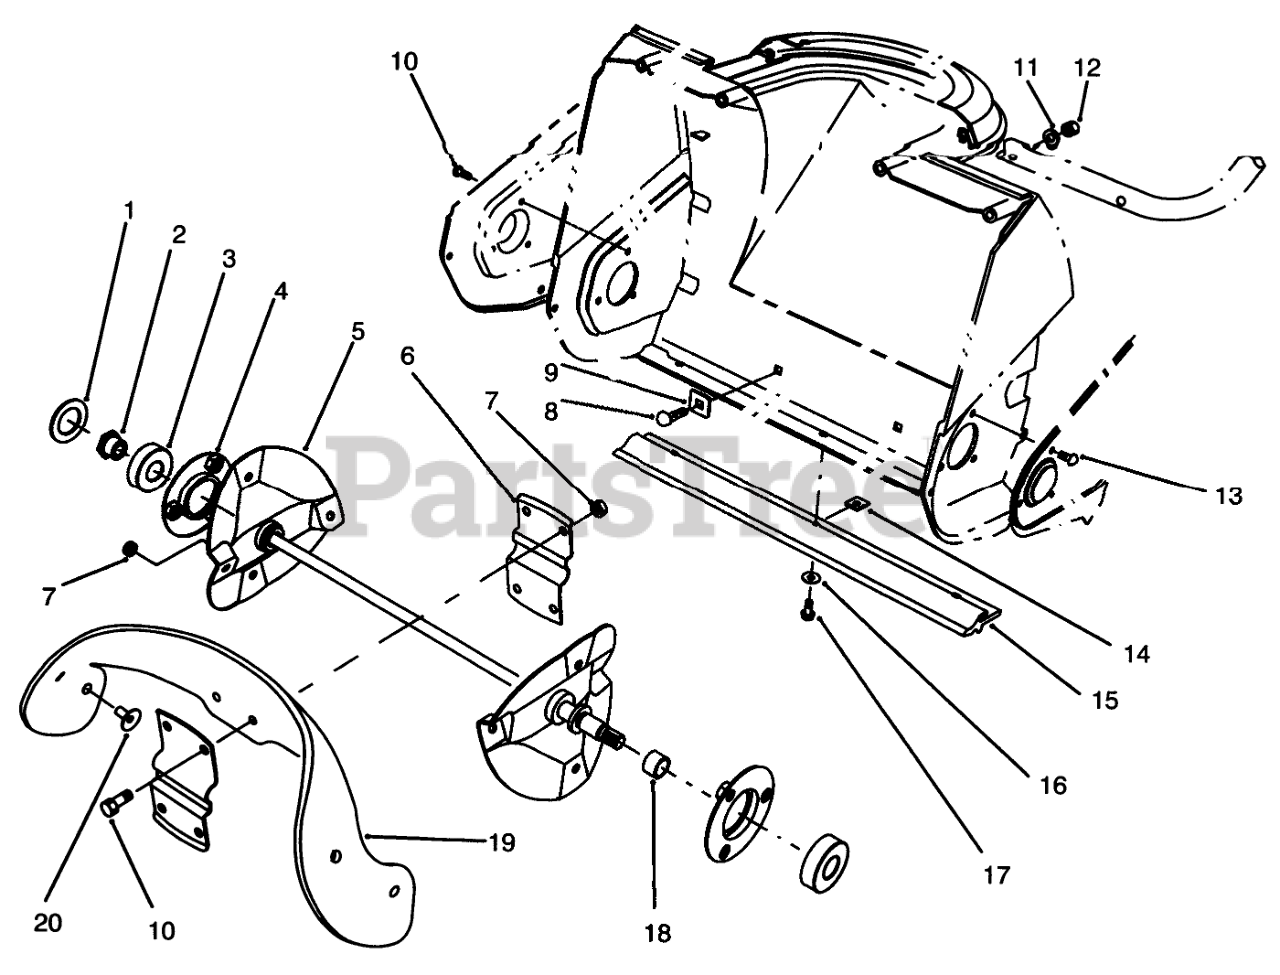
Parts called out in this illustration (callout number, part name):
1	WASHER-RUBBER
3	BEARING-BALL
4	FLANGE BEARING ASM
5	Rotor
6	Support-Rotor
7	NUT-LOCK, NI
8	SCREW-CARR
9	WASHER-SQUARE
10	SCREW-HHF
11	WASHER
12	NUT-LOCK, NI
13	SCREW-HH
14	NUT-CLIP, U
15	SCRAPER
16	WASHER-FLAT
17	SCREW-HWHTF
18	SPACER
19	BLADE-ROTOR
20	SCREW
